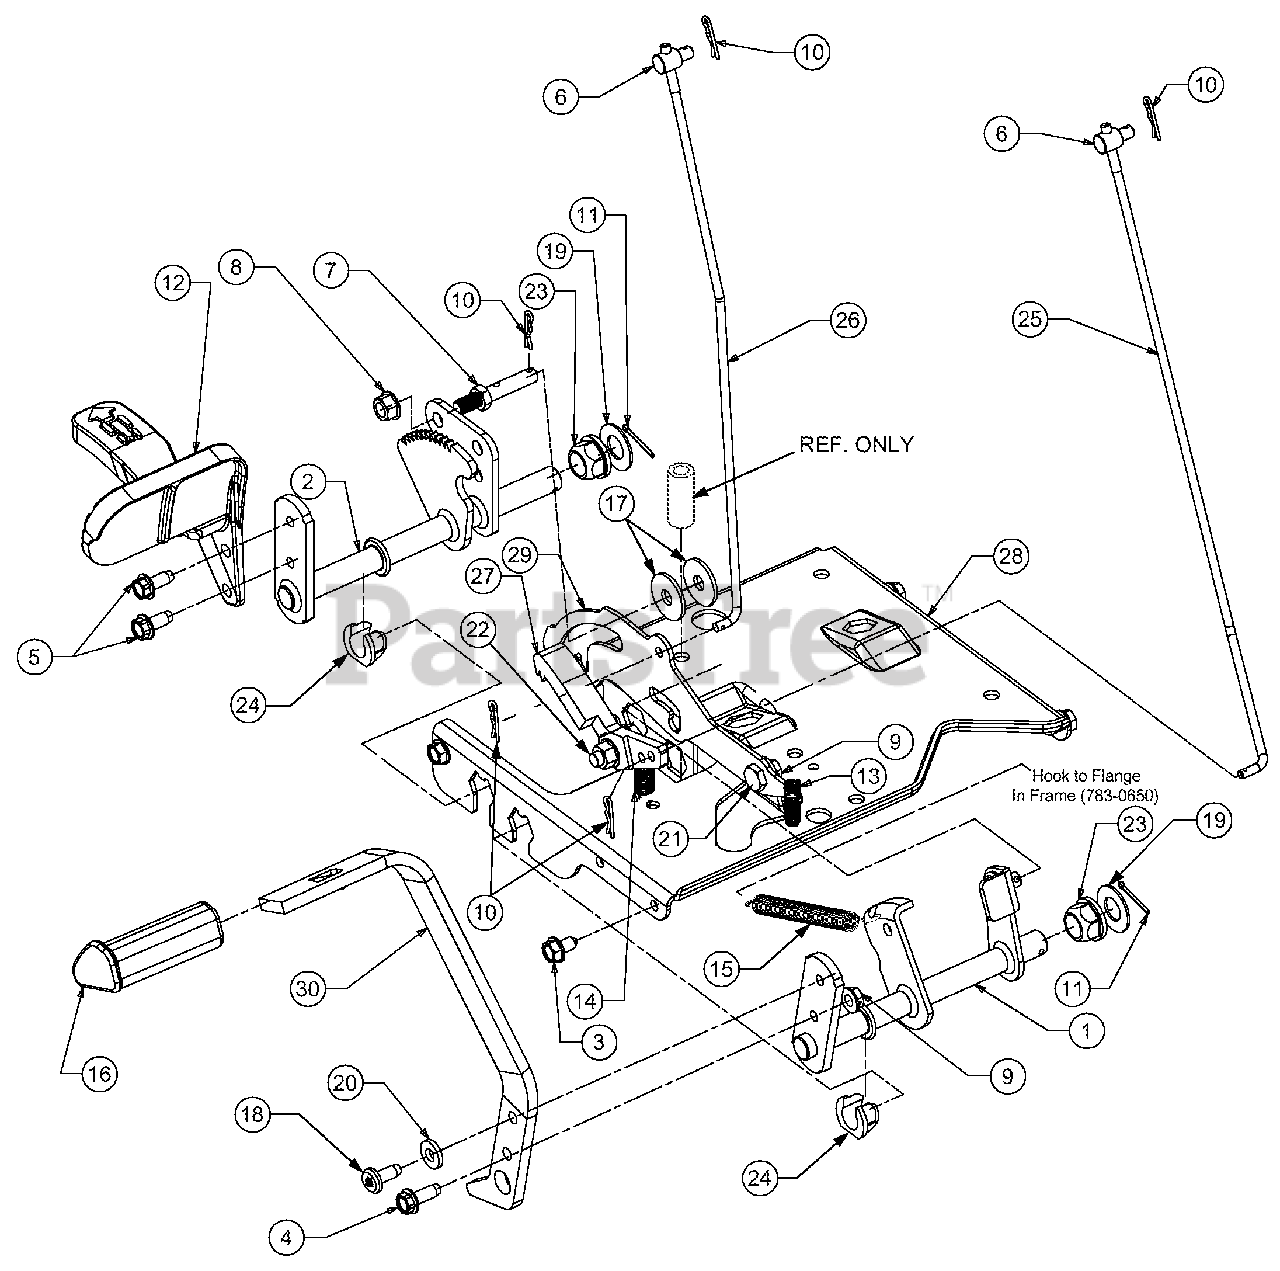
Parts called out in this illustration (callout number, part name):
3	Screw, Self-tapping, 5/16-12, 0.75
4	Screw, Self-tapping, 5/16-18, 0.875
5	Screw, 5/16-18, 0.750
6	Adjustment Ferrule 1/4-20 x 1.0
7	Pin, 3/8-16, 3/8 x 2.43 Lg
8	Nut, Flange Lock, 3/8-16
9	Nut, Flange Lock, 5/16-18, Gr5
10	Pin, Cotter, .072 Dia. x 1.13 Lg
11	Pin, Cotter, 3/32, 1.0
12	Pedal, Control
13	Spring, Compression, .405 x 1.17
14	Spring, Extension, .50 OD x 1.41 Lg
15	Spring, Extension, .50 Dia x 6.37 Lg
16	Pad, Brake, Control
17	Washer, Flat, .411 x 1.25 x .100
18	Screw, Torx Hd. Tapp. 5/16-18 x .75
19	Washer, Flat .64 ID x 1.24 x .06
20	Washer, Flat, .344 x .750 x .120
21	Shoulder, Screw .437 x 1.62 Lg
22	Screw, Shoulder, .500 Dia x .434
23	Bearing, Hex Flange
24	Bearing, Hex Flange, .628 ID, Split
25	Rod, Control, Cruise
26	Rod, Control, Brake Lock
27	Latch, Cruise
29	Bracket, Lockout, Hydro
30	Pedal, Brake
